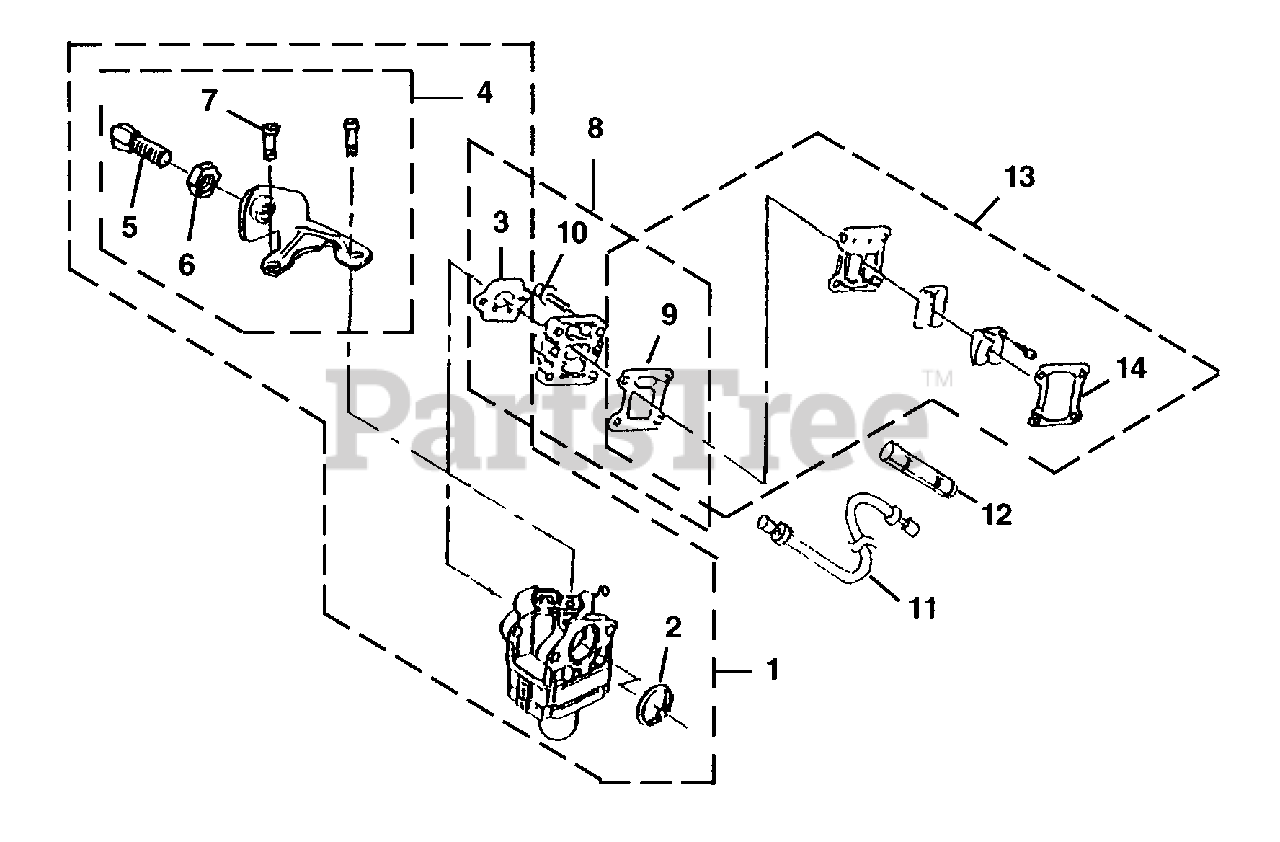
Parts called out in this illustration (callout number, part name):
1	CARBURETOR ASSY
2	RING-Packing
3	GASKET-Carburetor
4	CABLE BRACKET
5	SCREW-Cable Adjust
6	NUT-Cable Adjust
7	SCREW-Throttle Collar
8	HEAT DAM ASSEMBLY
9	GASKET-Heat Dam
10	SCREW-Socket Hd (M5 x 20)
11	CABLE-Throttle
12	CASE-Connector
13	REED VALVE ASSY
14	GASKET-Reed Valve
